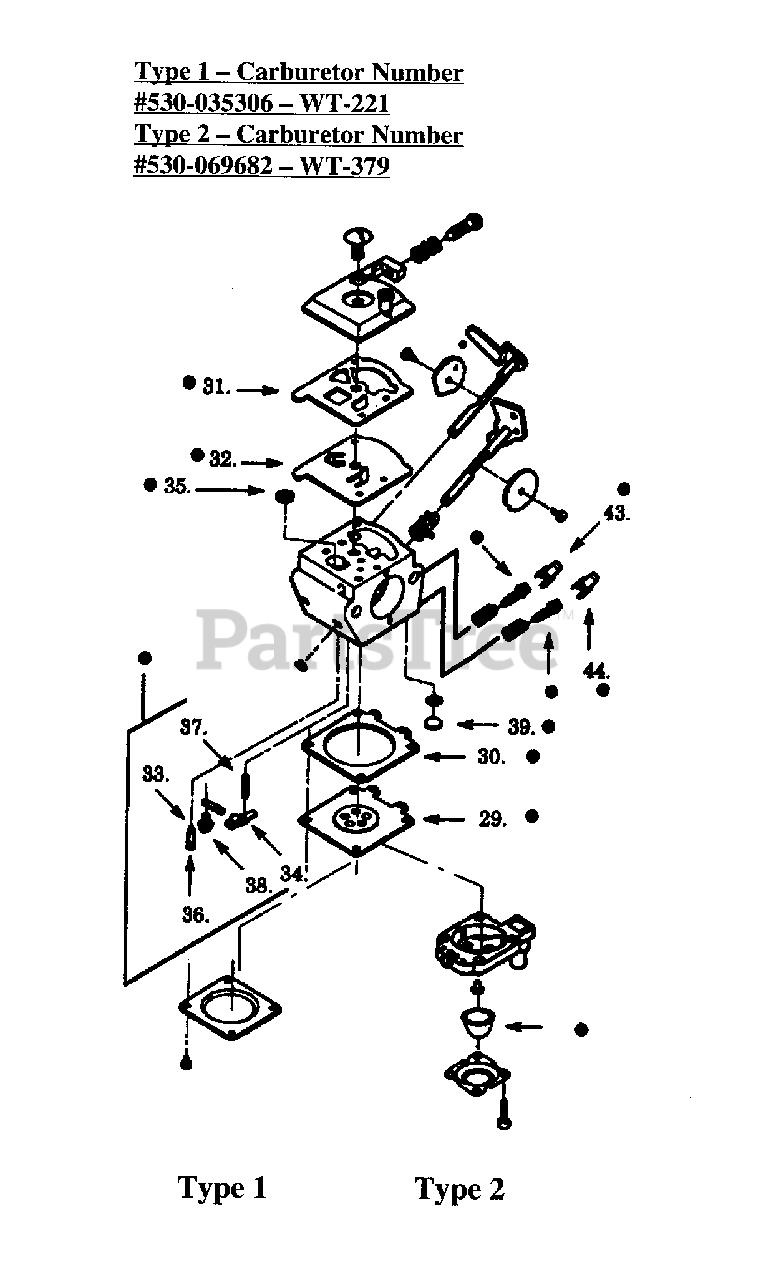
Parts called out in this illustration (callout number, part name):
2	LEAD
3	SCREW 8-16 X 9/16 (PLAS
6	SCREW-10-16 X 1-3/8 PLA
8	TRIGGER
9	THROTTLE LOCK
12	REPL BY 530 04 78-79
14	ANTIVIBE MOUNT
15	CLUTCH DRUM
17	PLATE-GEARBOX COVER
18	BLADE BUSHING
19	BLADE ASSY
24	ISOLATOR PLATE
25	COVER
27	SCREW-10-14 X 13/16 (PL
28	GEARBOX ASSY
29	METERING DIAPHRAGM
32	PUMP DIAPHRAGM
33	FULCRUM PIN
35	SCREEN-DUTCH TWILL INLE
36	VALVE/INLET.
39	WELCH PLUG
40	REPL BY 530 06 98-44
43	LIMITER CAP (LOW-BLUE)
5300353-12	CARBURETOR KIT
5300696-56	REPAIR KIT
